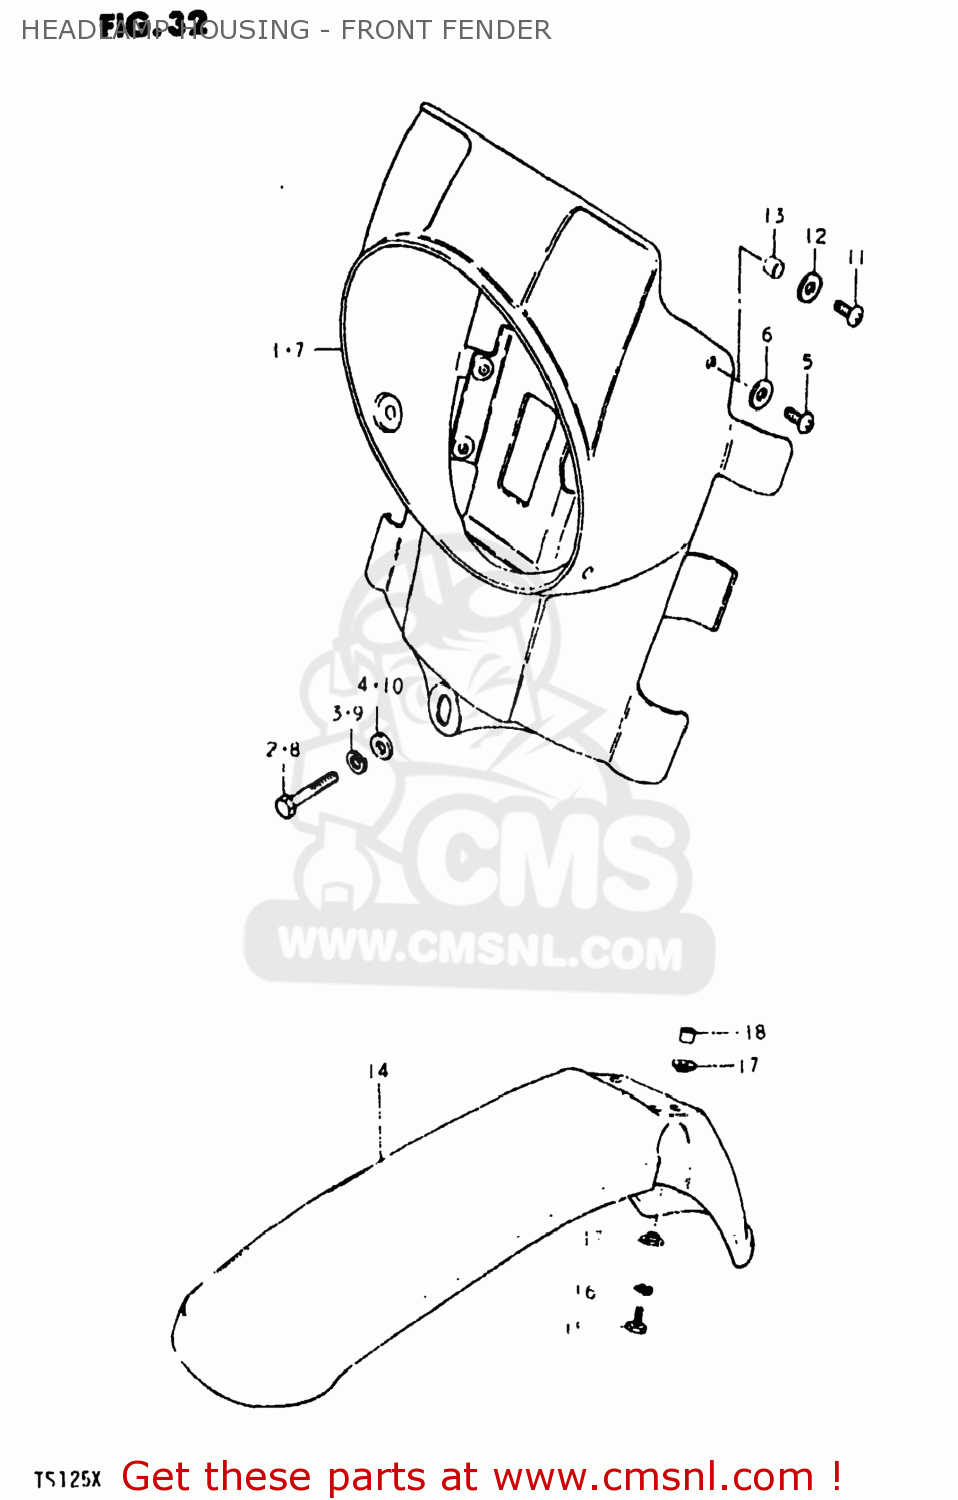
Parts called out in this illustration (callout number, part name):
1	HOUSING,HEADLAMP
2	BOLT
3	LOCK WASHER
4	WASHER
5	SCREW
6	WASHER (5.5X16X1.2)
7	HOUSING,HEADLAMP
8	BOLT
9	LOCK WASHER
10	WASHER
11	SCREW
12	WASHER (5.5X18X1.6)
13	SPACER (5.5X8X4)
14	FENDER,FRONT
15	BOLT
16	LOCK WASHER
17	SPACER
18	SPACER
